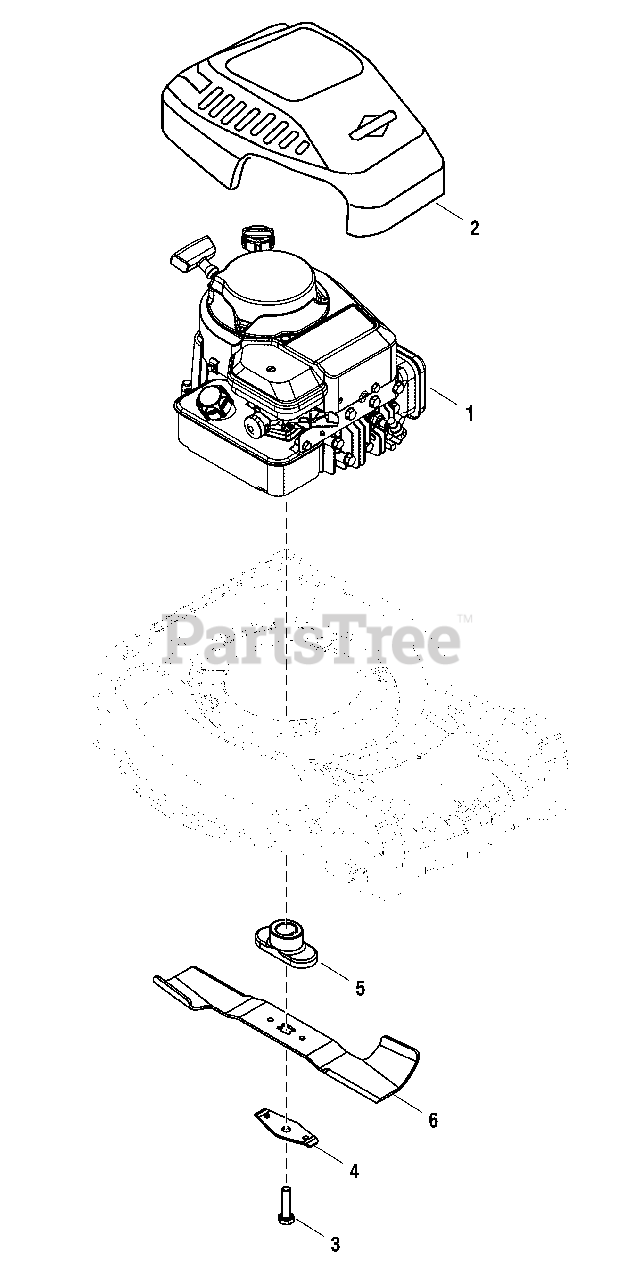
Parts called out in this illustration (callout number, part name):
1	* ENGINE, Briggs & Stratton, Mod. 08P602-0011-H1
3	SCREW Hex, 3/8-24 x 1-1/2
4	SUPPORT, Blade Bell
5	BLADE ADAPTER
